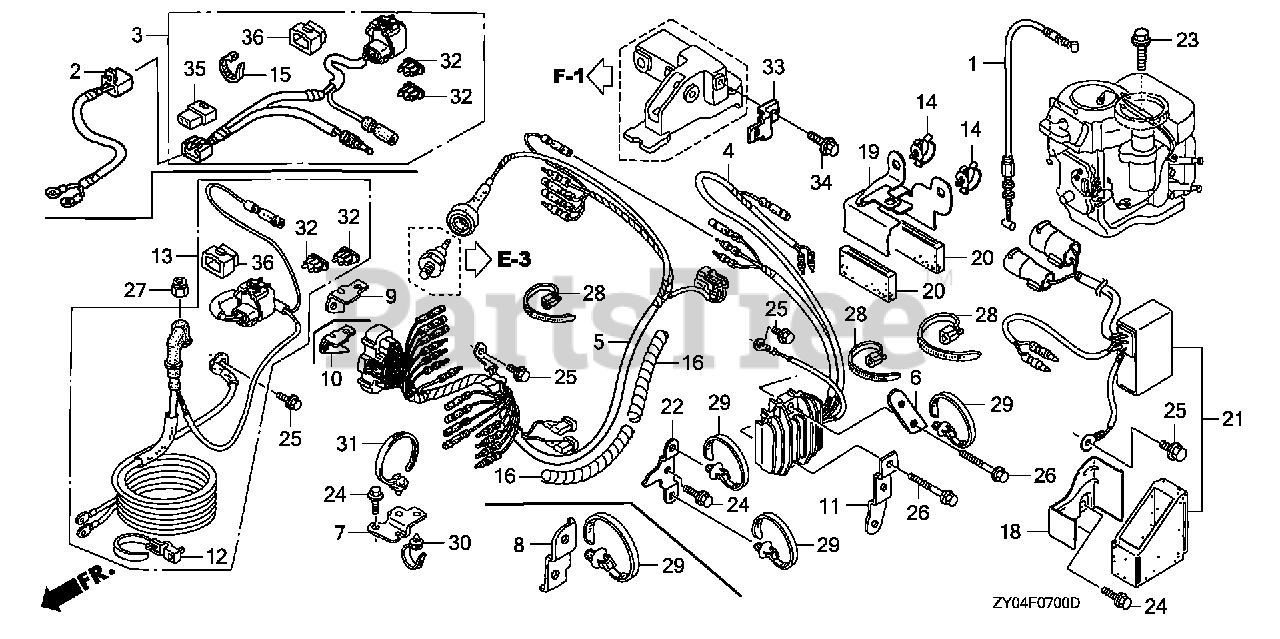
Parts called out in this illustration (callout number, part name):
1	CABLE, NEUTRAL STARTING
4	RECTIFIER ASSY., REGULATOR
5	WIRE HARNESS ASSY. (SELF STARTER)
6	BRACKET, CLIP F
7	BRACKET, STARTER CABLE
8	BRACKET, CLIP B
9	BRACKET, FUSE CASE
11	BRACKET, E-CLIP
12	BAND, WIRE
13	CABLE ASSY., STARTER
16	TUBE, SPIRAL A
23	BOLT, FLANGE (6X20)
24	BOLT, FLANGE (6X14) (CT200)
25	BOLT, FLANGE (6X12)
26	BOLT, FLANGE (6X26) (CT200)
27	NUT, LOCK (6MM)
28	TIE, CABLE
29	CLIP, HARNESS BAND (151.5MM) (NATURAL)
30	BAND, WIRE HARNESS (123.5MM) (BLUE)
32	FUSE, BLADE (20A)
36	COVER ASSY., FUSE (20A)
